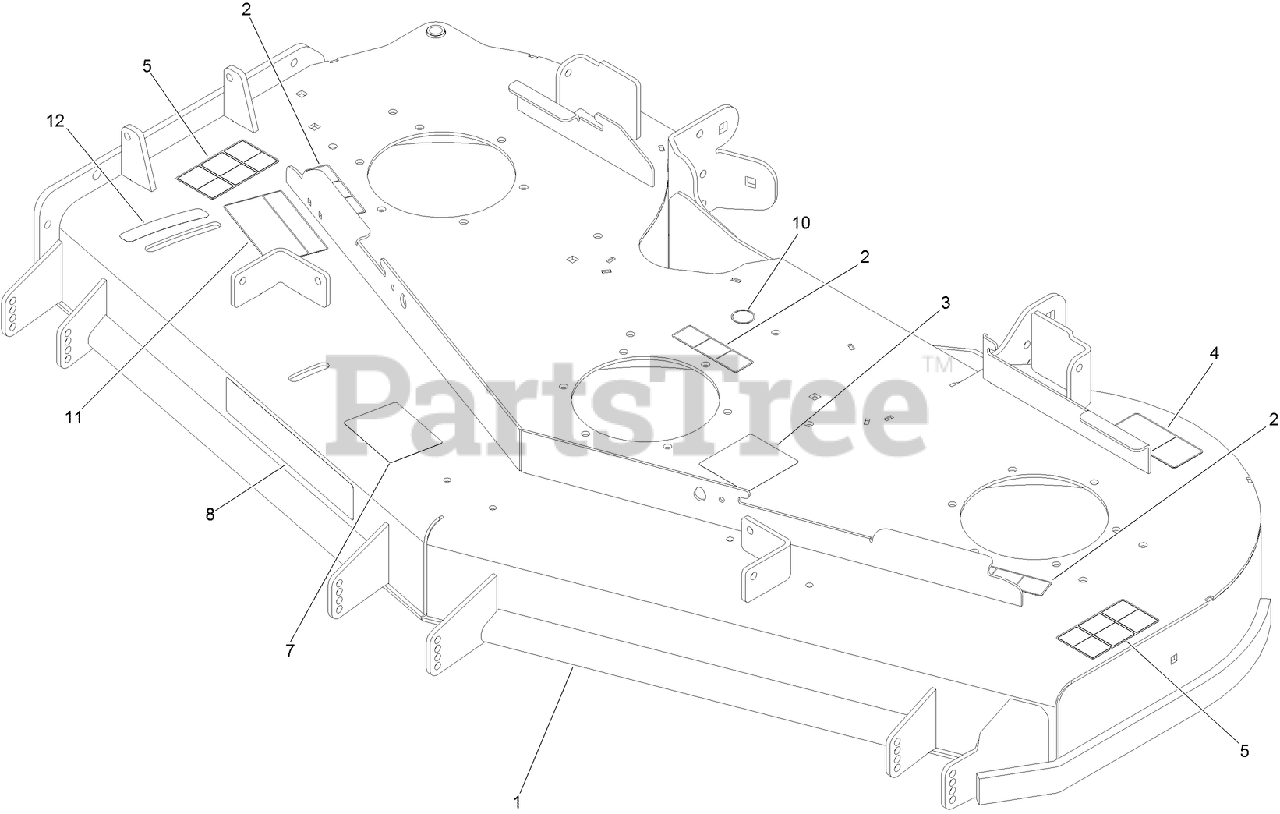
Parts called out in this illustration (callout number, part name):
1	DECK DECAL ASM
2	DECAL-COVER, MISSING
3	DECAL-ROUTING, DECK BELT
4	DECAL-TORQUE, BLADE BOLT
5	DECAL-DANGER
7	DECAL-SCALP, ANTI
10	DECAL-GREASE
11	DECAL-ADJUSTMENT, BAFFLE
12	DECAL-SETTING, BAFFLE
